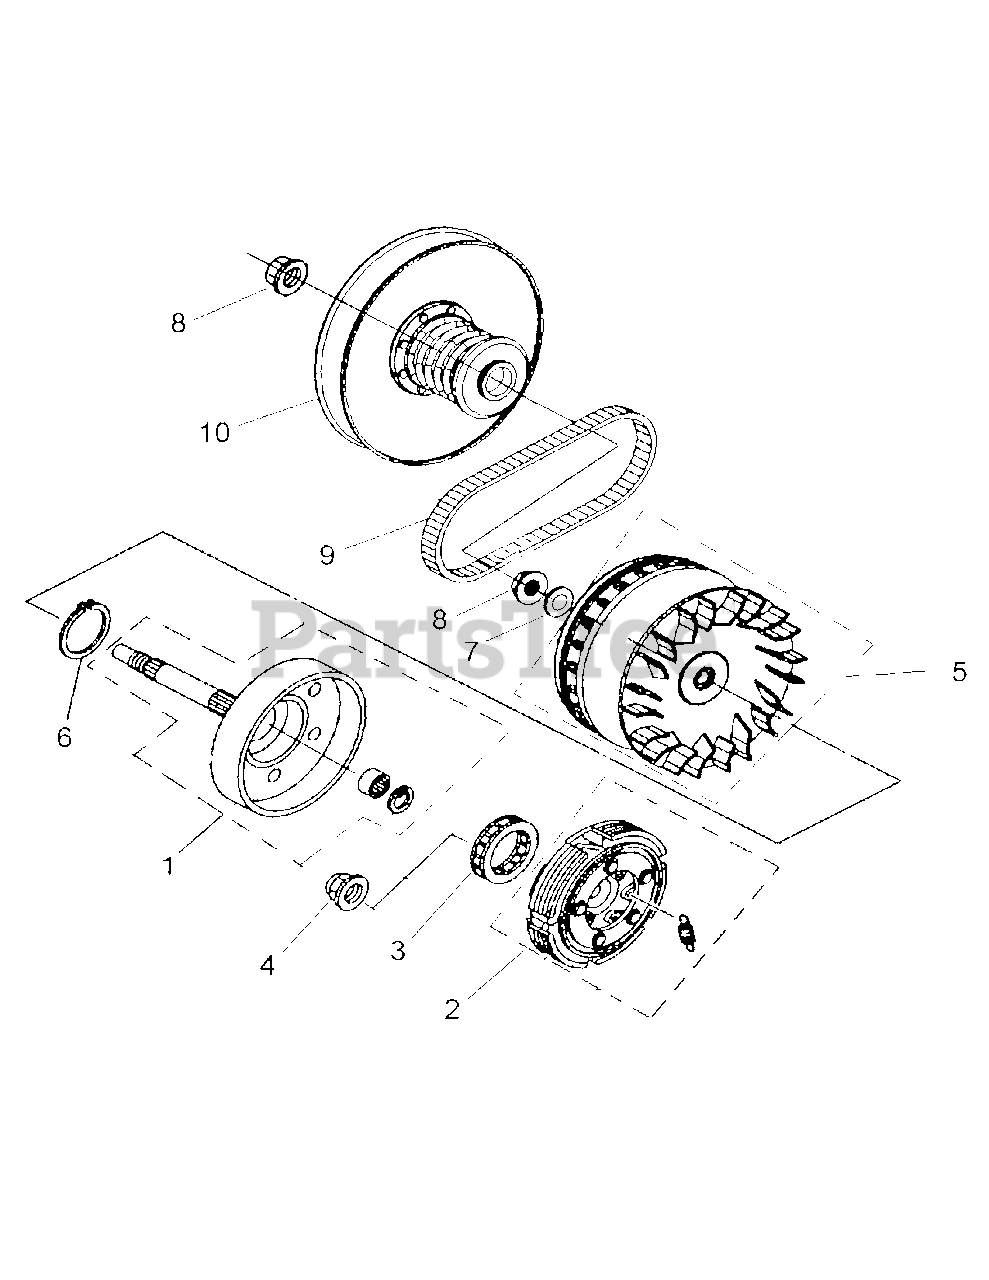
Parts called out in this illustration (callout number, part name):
1	Cover-Outer Clutch
2	Clutch-Complete
3	One Way Machine-Comp
5	Cvt Clutch-Driver
9	Belt
10	Cvt Hypo Clutch-Driven
